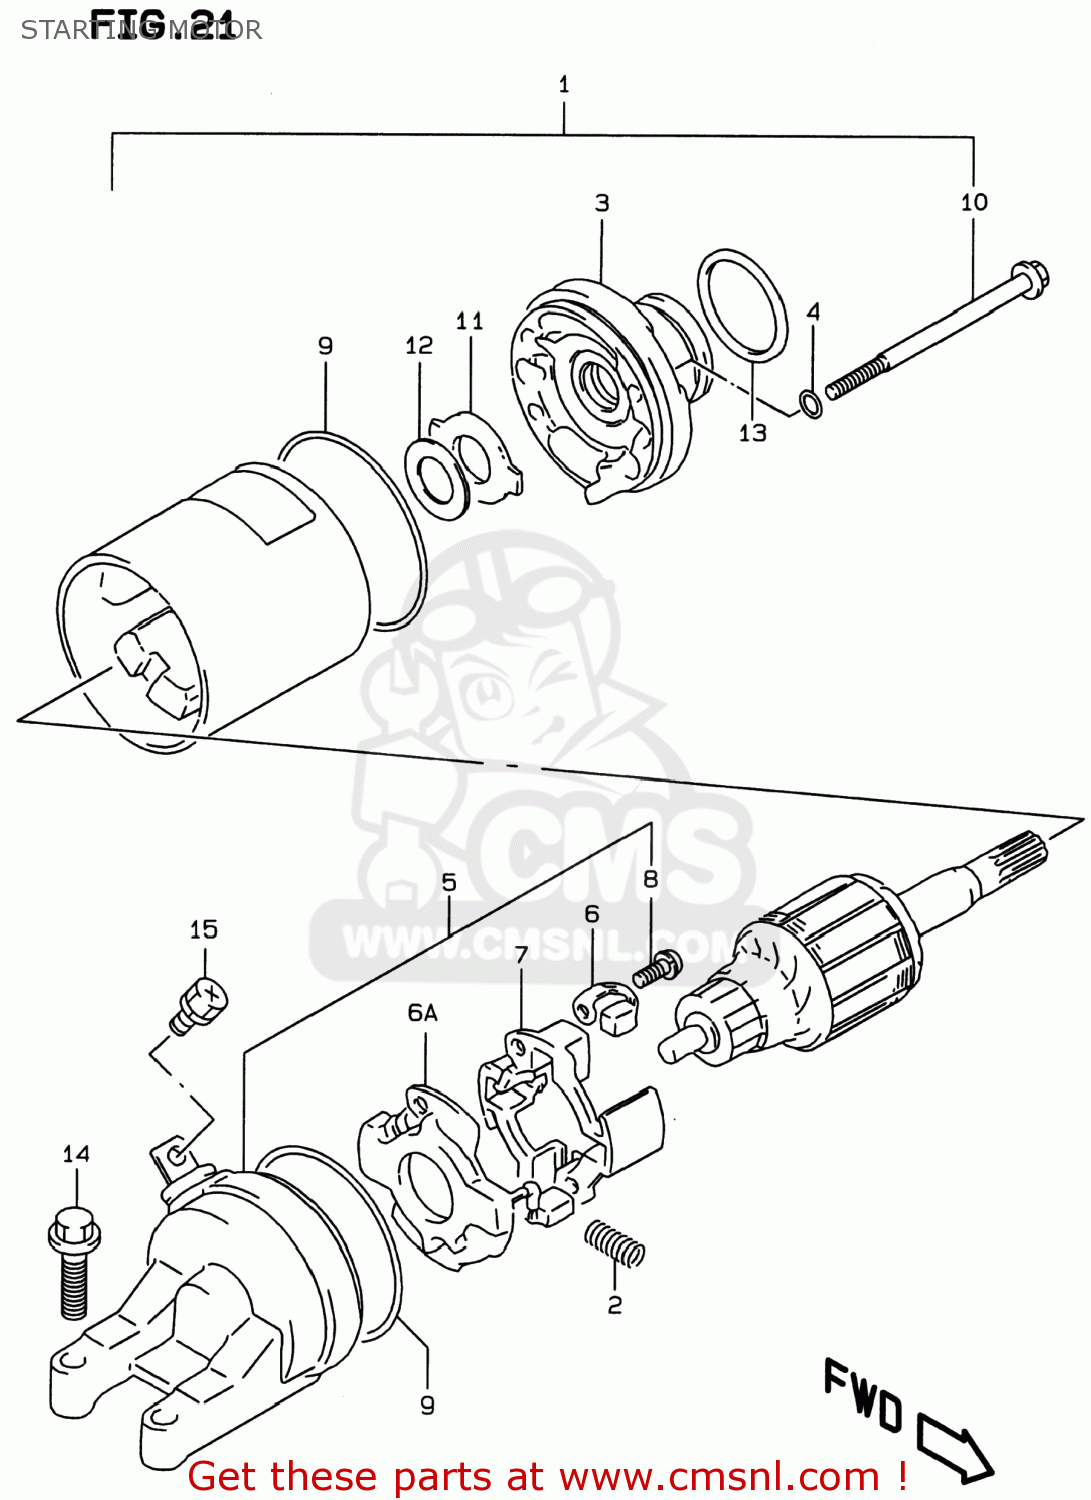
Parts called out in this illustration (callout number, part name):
1	MOTOR ASSEMBLY,STARTING
2	SPRING
3	BRACKET
4	O RING
5	FRAME ASSY,COMMUTATOR END
6	BRUSH
6A	BRUSH SUB ASSY,STARTER
7	HOLDER,BRUSH
8	SCREW
9	O RING
10	BOLT
11	PLATE,LOCK
12	SHIM
13	O RING(D:3,ID:24.5)
14	SCREW (6X25)
15	SCREW(5X8)
